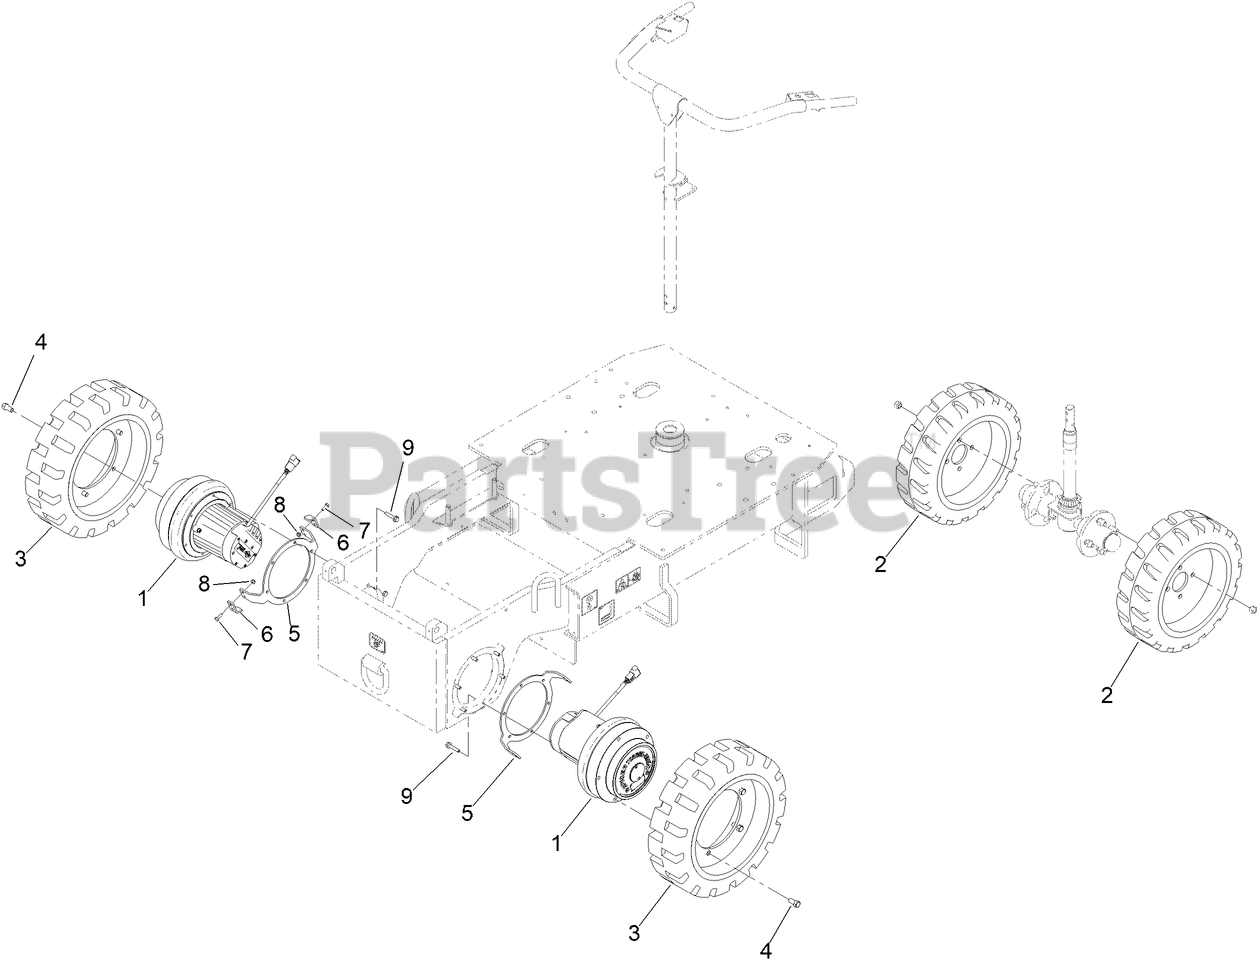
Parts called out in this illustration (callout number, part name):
1	MOTOR/GEN TORQUE-HUB ASM-3KW 31:1 RDCTN
2	TIRE-SOLID
3	TIRE-SOLID
4	SCREW-HH, LUG M12 X 1.50
5	SPACER-WHEEL
6	PLATE-WIPER
7	SCREW-HH
8	NUT-HF
9	SCREW-HHF
